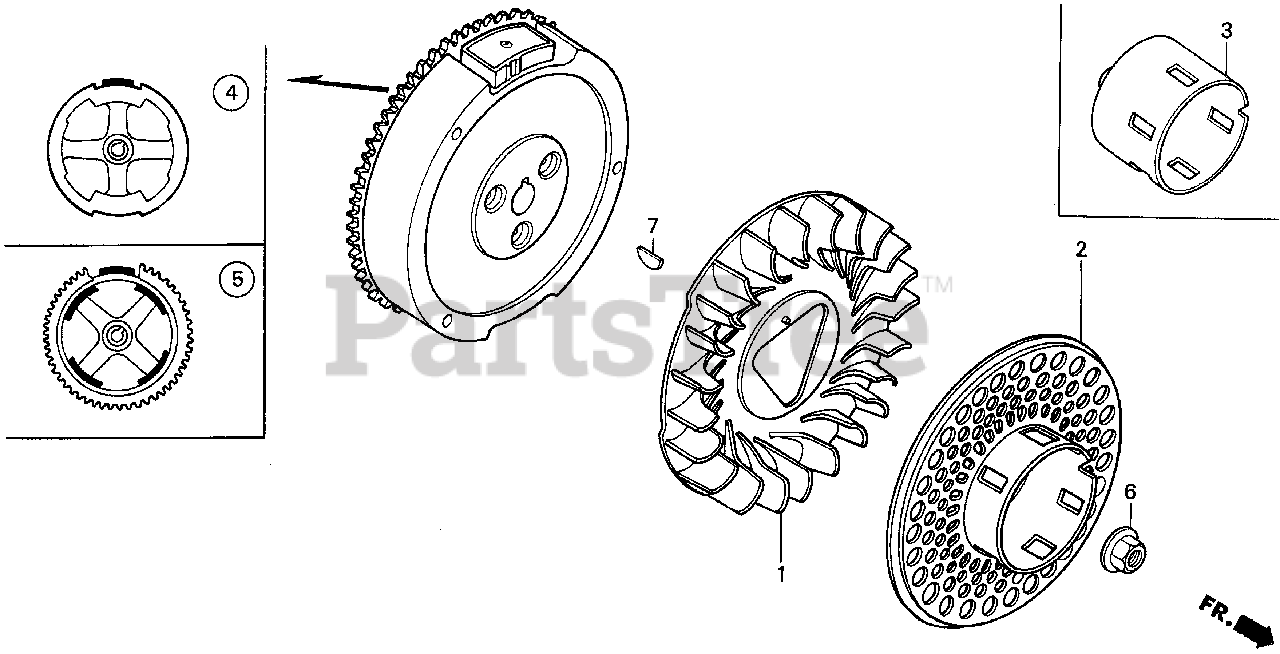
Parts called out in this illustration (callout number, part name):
1	FAN, COOLING
2	PULLEY, STARTER (SCREEN GRID)
4	FLYWHEEL
6	NUT, SPECIAL (16MM) (1)
6	NUT, SPECIAL (16MM)
7	KEY, SPECIAL WOODRUFF (25X18)
